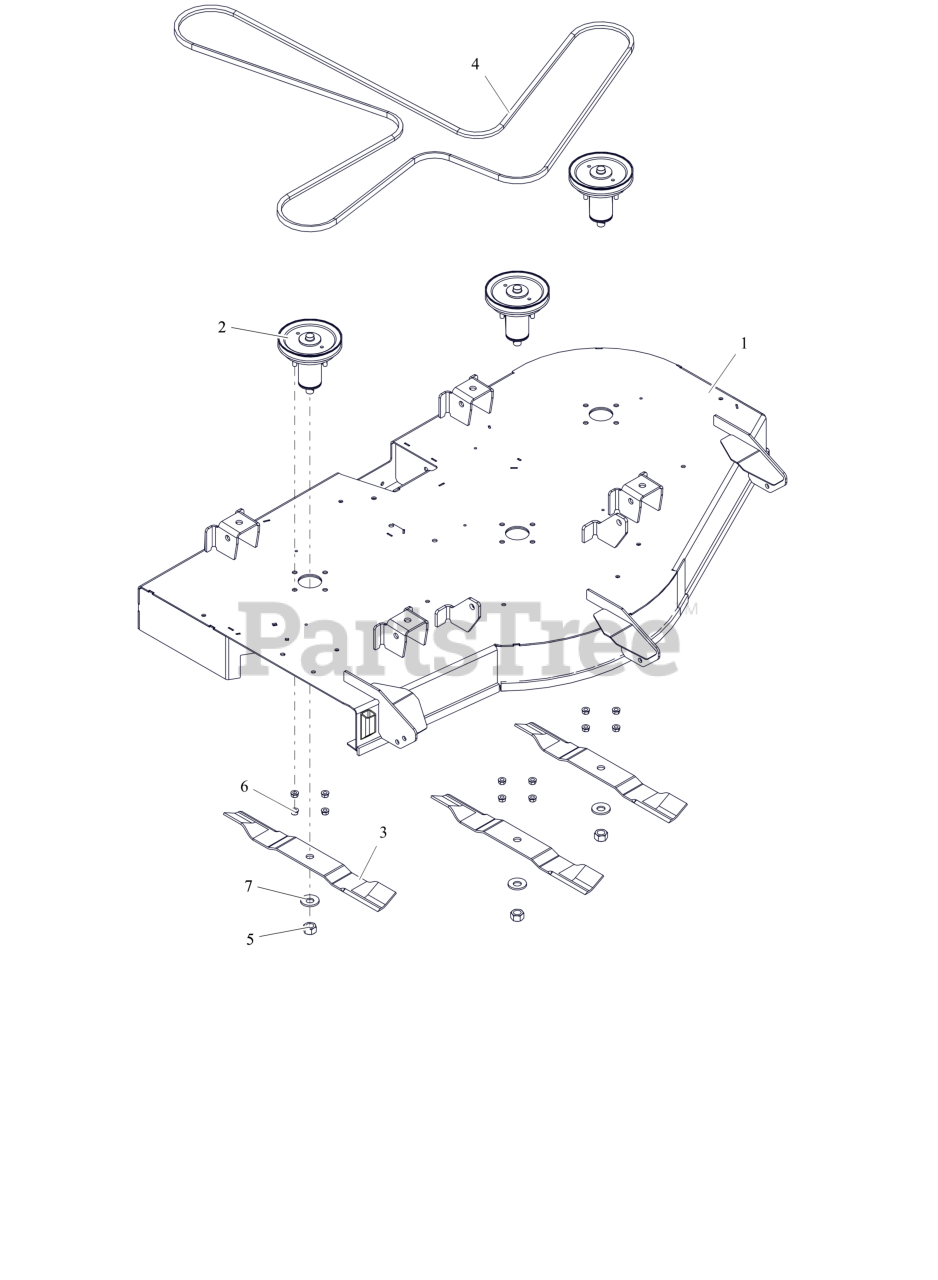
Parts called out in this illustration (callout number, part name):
1	WLDMT, DECK 52" (ORANGE)
2	KIT- DECK SPINDLE ASSM- 52"
3	BLADE, 18" - 30 DEG .5 OFFSET
4	V-BELT, HA-WRAPPED
5	NUT-STD .625-18 ZCC
6	NUT,LK-CTR-FLG .31-18 GF ZCC
7	WSHR-BLVL .669X1.535X.138
